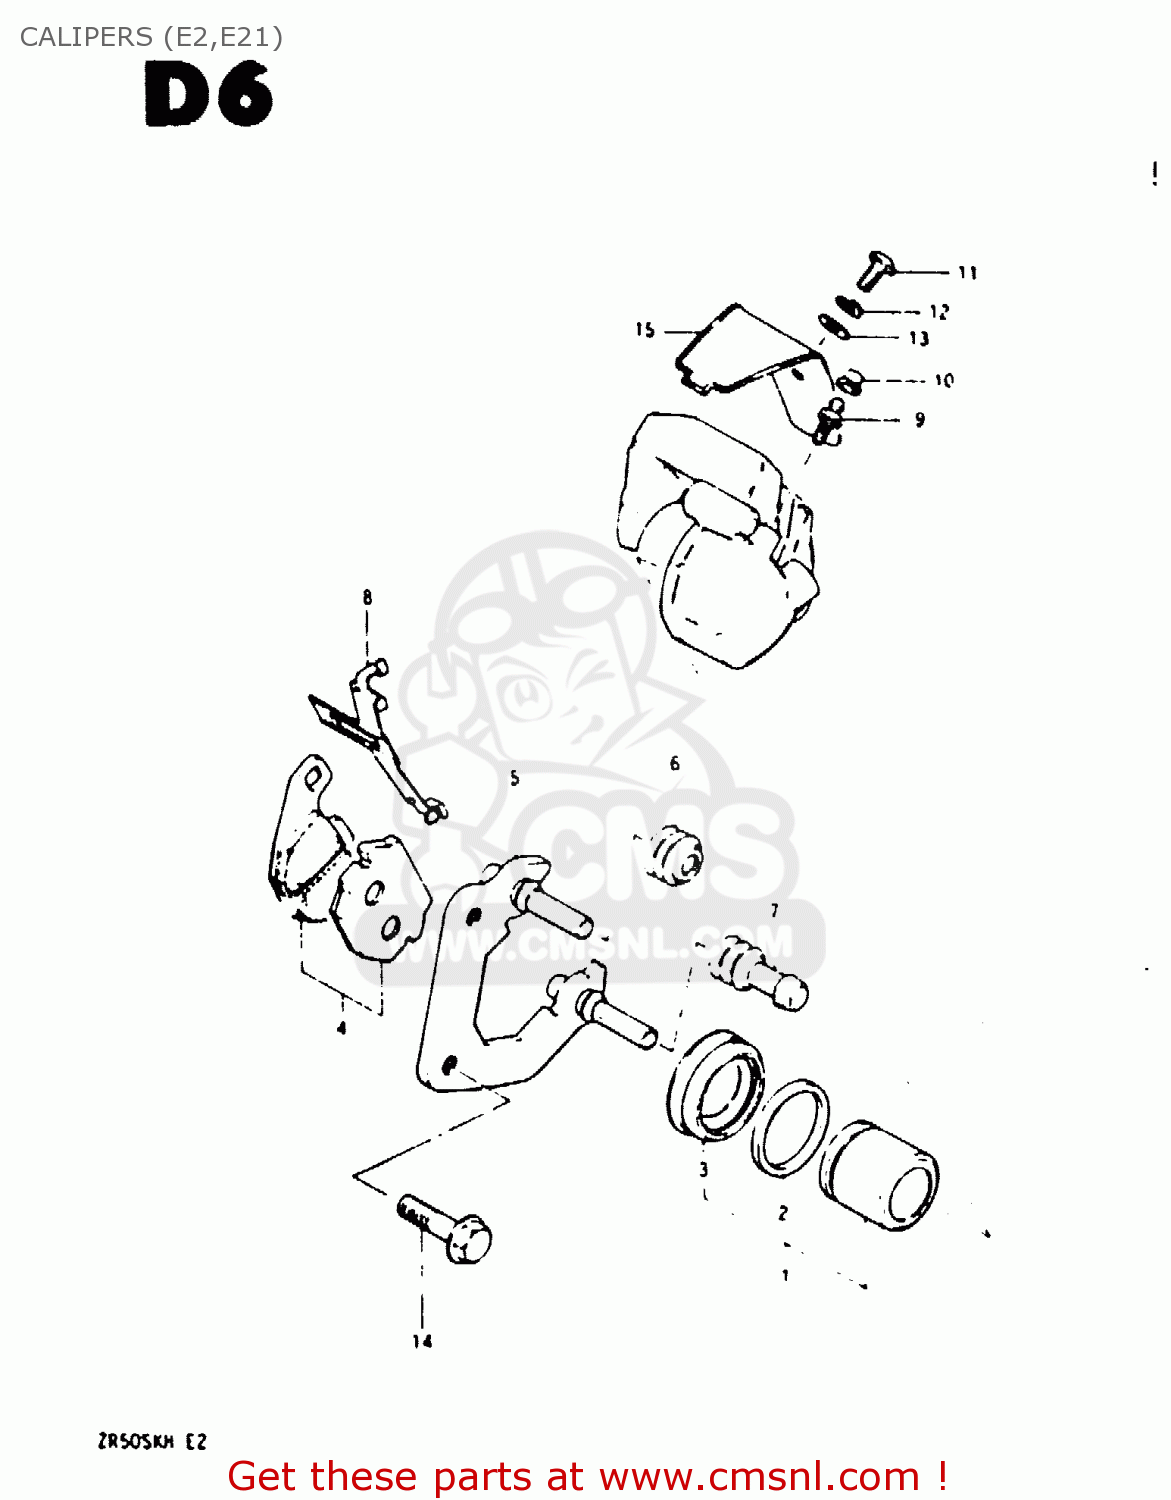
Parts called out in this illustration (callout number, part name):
1	PISTON SET
2	SEAL,PISTON
3	BOOT,PISTON
4	PAD SET
5	CARRIER,L
6	BOOT,AXLE
7	INSULATOR,AXLE
8	SPRING,PAD
9	BLEEDER
10	CAP,BREATHER
11	SCREW
12	WASHER,LOCK
13	WASHER,5MM
14	BOLT 8X30
15	PROTECTOR,CALIPER
